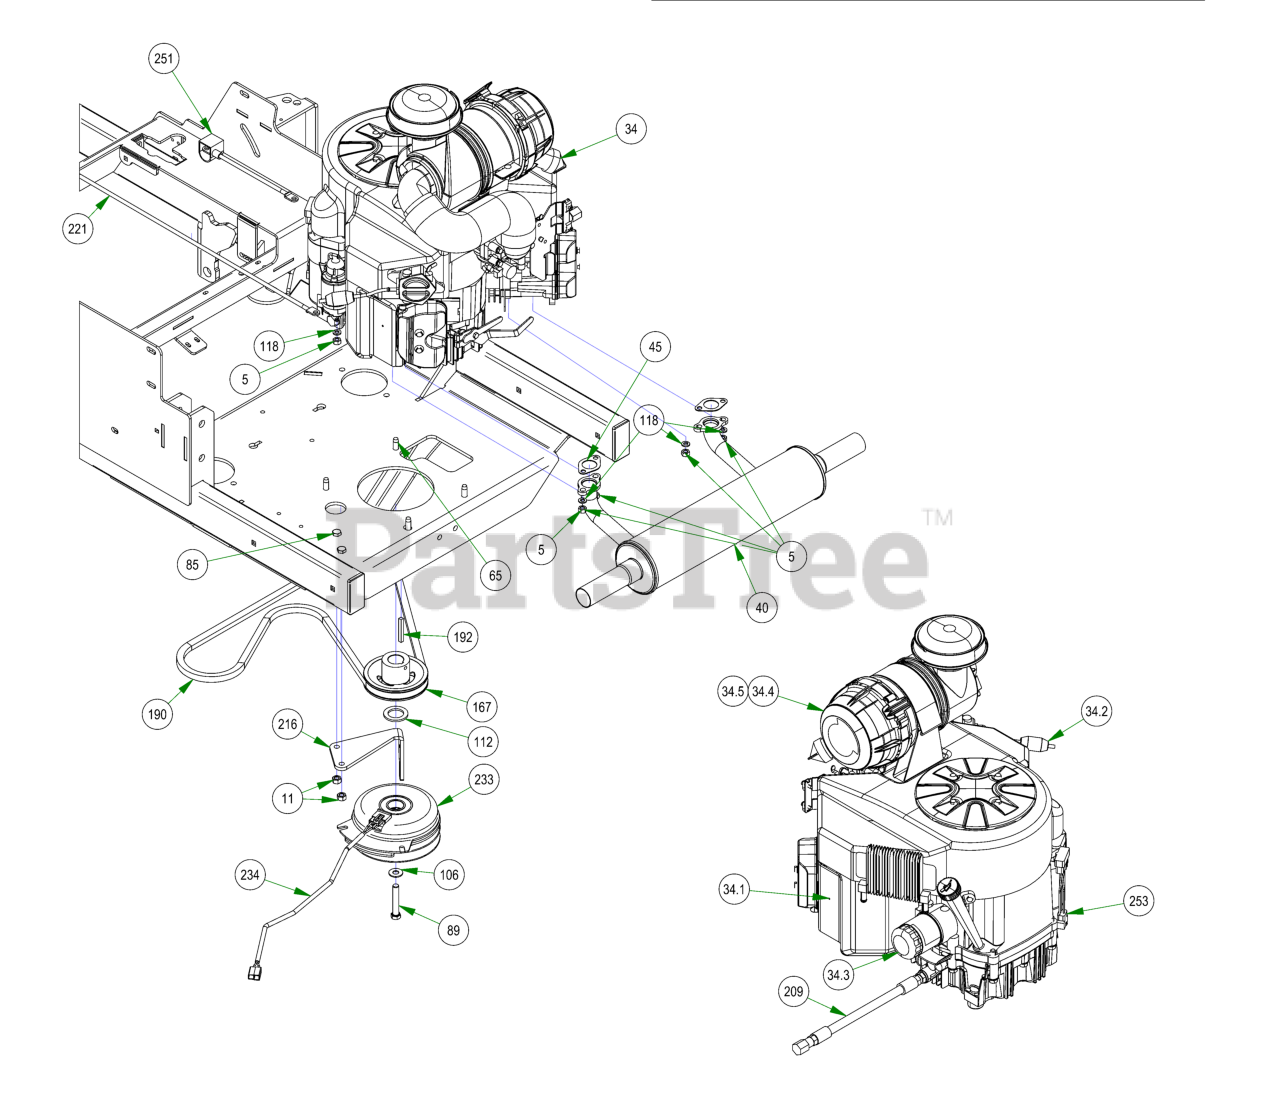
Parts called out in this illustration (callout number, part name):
5	M8-1.25 DIN 934 HEX NUT (CL.8) ZINC
11	3/8-16 HEX NUT ZINC
32	1 1/2 x 3 Frame Plug
34	Kawasaki FX850 Engine
34.1	Spark Plug - Kawasaki
34.2	Universal Inline Fuel Filter
34.3	Oil Filter
34.4	Canister Air Filter- Outer
34.5	Canister Air Filter- Inner
40	2019 Rebel/Rogue Kawasaki 850 Muffler
45	Exhaust Gasket
65	3/8-16 X 1-1/8HEX WASHER UNSLOT SERRATED
85	3/8-16 X 1-1/4 HEX CAP SCREW (GR.5) ZINC
89	7/16-20 X 2-1/2 HEX Bolt GR 8 W/ Patch
106	3/8 FLAT WASHER USS (1" OD) ZINC
112	1.140 ID X 1.750 OD X .132 THICK FLAT WASHER PLAIN
118	5/16 SPLIT LOCKWASHER ZINC
167	4 3/4 Motor Pulley
190	2019 Rogue Pump Belt 68"
192	1/4 X 2 SQ MACHINERY KEY 1018 STL PLAIN
209	Kawasaki Oil Drain
216	PTO Engager Holder
221	24" Red Battery Cable
233	Clutch Assembly
234	Clutch Pigtail
235	2023 Rogue Frame - Painted
251	Starter Cable
253	2019 Harness Adaptor-Gen2 FX-ALL
